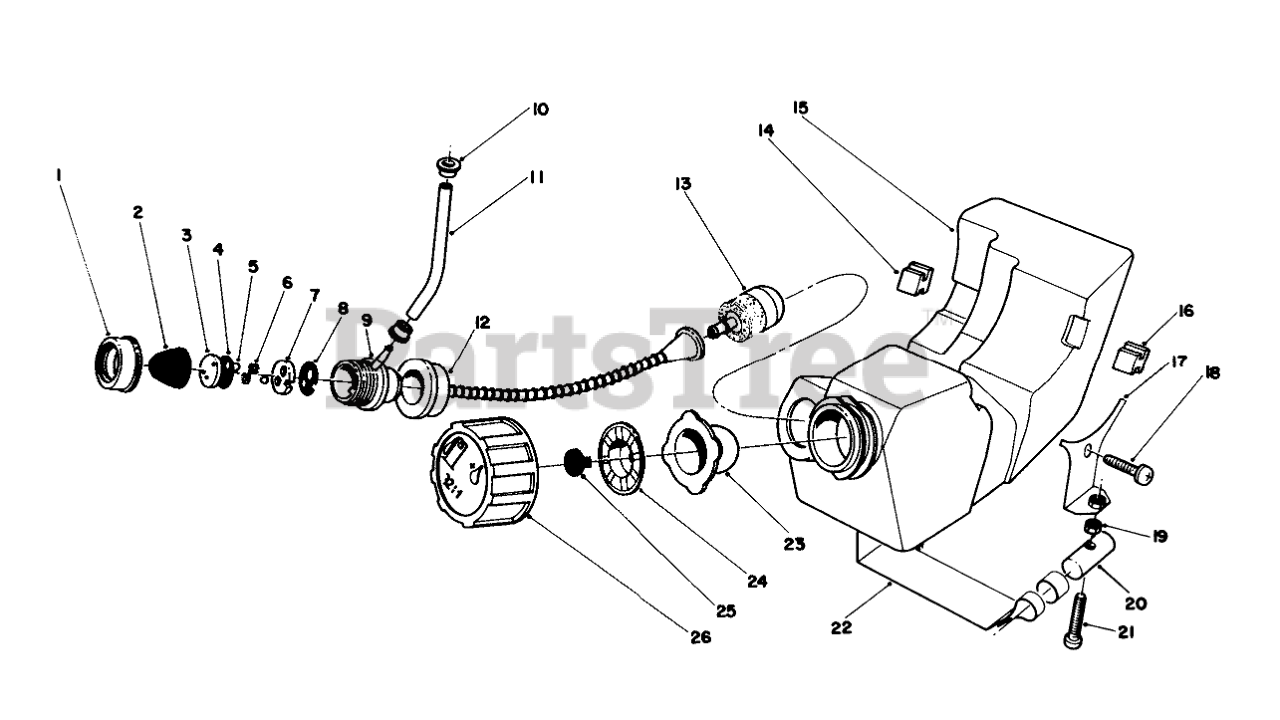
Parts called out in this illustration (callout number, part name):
1	PUMP CAP
3	SEAT VALVE
4	GASKET
6	SPONGE
7	SEAT VALVE
8	GASKET
9	Primer Pump Assembly (Incl. Ref. #1-8)
11	TUBE, FUEL
12	SUCTION HOSE
13	FUEL FILTER
15	Fuel Tank Assembly (Incl. Ref. #1-9, 12, 13, 23-26)
17	Hanger-Tank
18	Screw
21	Screw
22	BAND, TANK
23	GASKET - PACKING
24	HOLDER
25	BREATHER VALVE
26	TANK CAP
